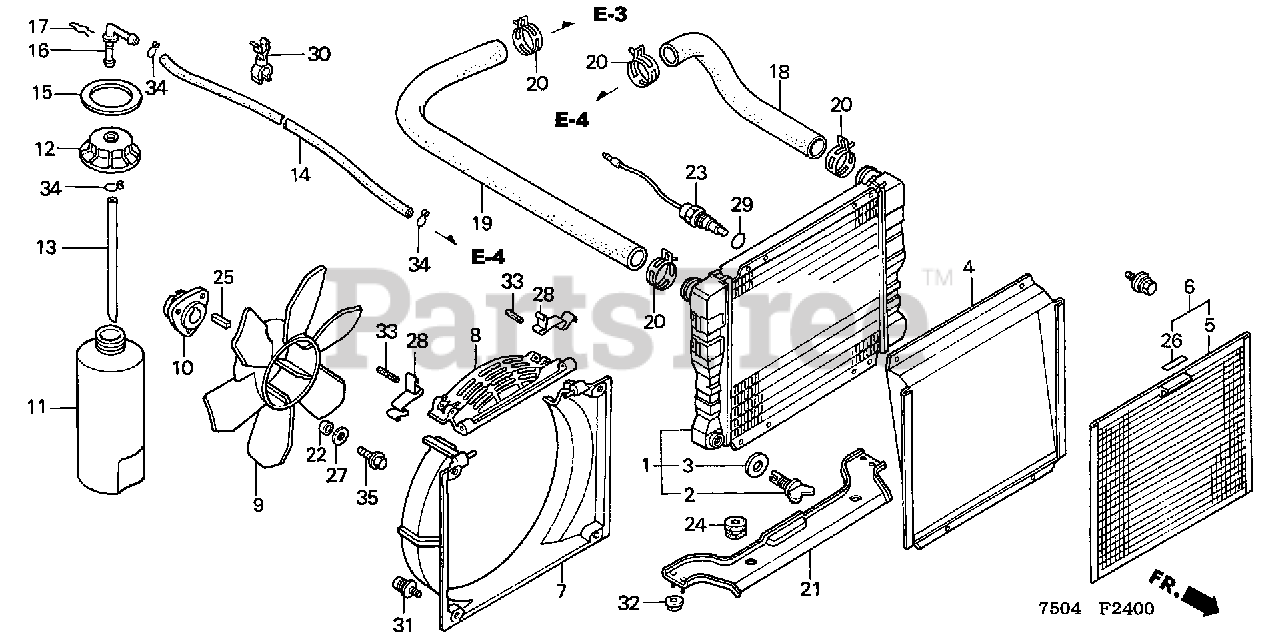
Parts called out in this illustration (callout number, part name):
2	VALVE, DRAIN (TOYO)
3	GASKET, DRAIN (TOYO)
4	GUIDE, FR. SCREEN
5	SCREEN, FR.
6	SCREEN, FR. (FOR COLD AREA)
7	SHROUD, RADIATOR (LOWER) (NOT AVAILABLE)
8	SHROUD, RADIATOR (UPPER)
9	FAN, COOLING
10	BOSS, COOLING FAN
11	TANK, RESERVE
12	CAP, RESERVE TANK
13	HOSE, RESERVE TANK
14	TUBE, RESERVE TANK
15	MARK, RESERVE TANK
16	JOINT, RESERVE TANK
17	CLIP, RESERVE TANK JOINT
18	HOSE A, WATER
19	HOSE B, WATER (NOT AVAILABLE)
20	CLIP, WATER HOSE
21	BRACKET, RADIATOR (LOWER)
22	COLLAR, FAN
23	SWITCH ASSY., THERMO (NOT AVAILABLE)
24	RUBBER B, BATTERY BOX
25	KEY (7X7X23) (NOT AVAILABLE)
26	MARK, FR. SCREEN
27	WASHER, PLAIN (6.5X15)
28	CLIP, RADIATOR SHROUD
29	O-RING (13.5X1.4)
30	CLIP, DOUBLE
31	SCREW-WASHER (6X12)
32	NUT, FLANGE (6MM)
33	PIN, SPRING (4X30)
34	CLIP, TUBE (C11)
35	BOLT, FLANGE (6X16)
